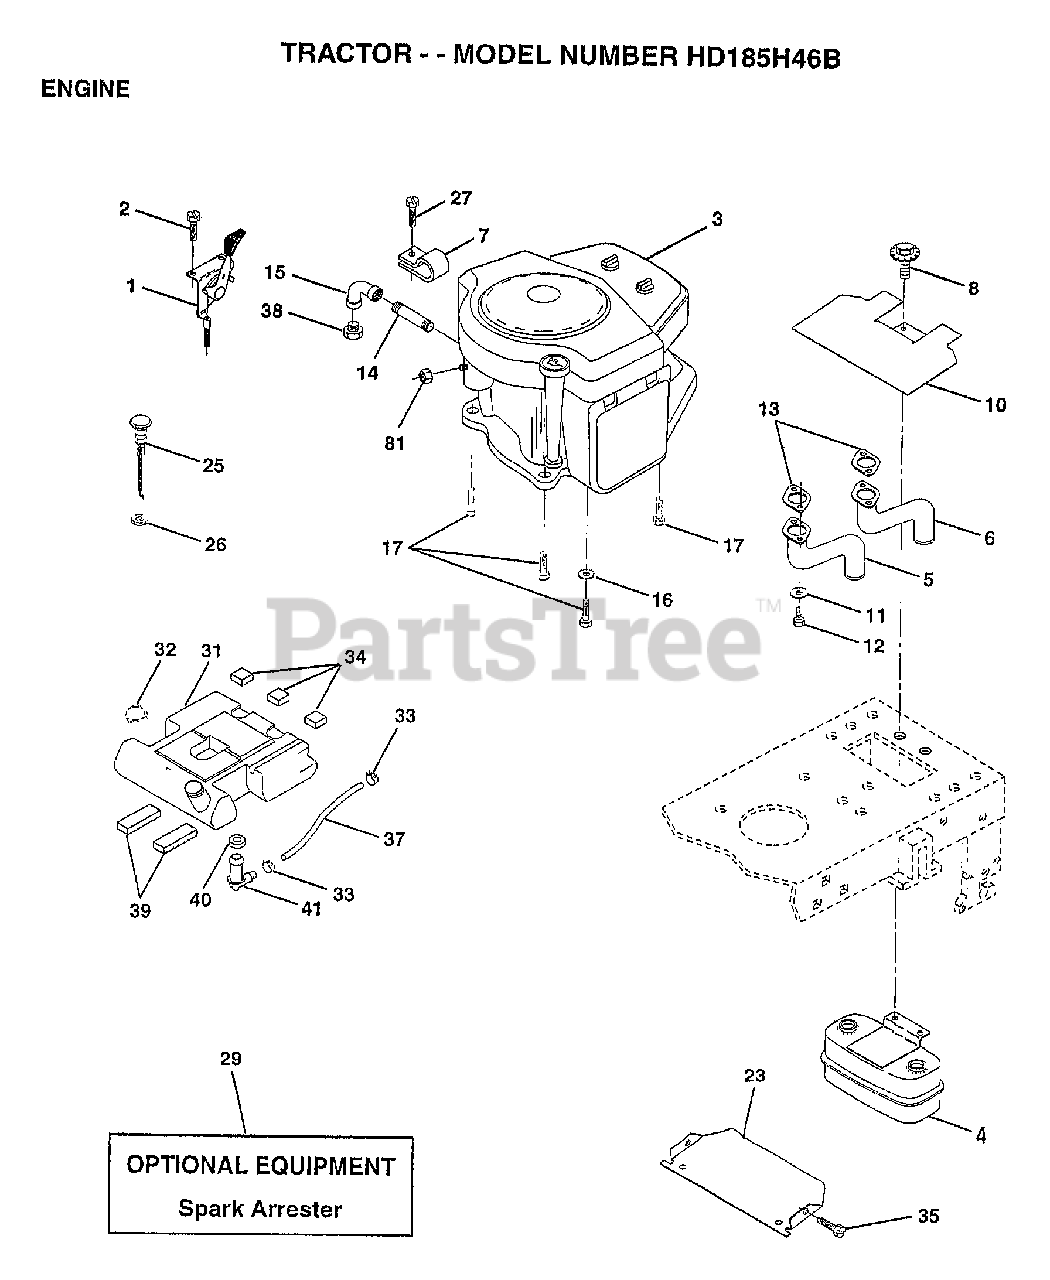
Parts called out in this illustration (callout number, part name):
1	CONTROL THRT 35.5
2	SCREW LT
4	MUFFLER.TW.LOTONE
5	EXHAUST.B&S.18.RH
6	EXHAUST.B&S.18.LH
7	CLAMP.TUBE.DBL.EN
8	BOLT.5/16-18.UNC
10	SHIELD.HEAT.
11	LOCKWASHER
13	GASKET MUFFLER
14	PIPE NIPPLE LT
15	ELBOW
16	LOCKWASHER
17	SCREW LT
23	SHIELD-HEAT
25	CONTROL.CHOKE.37
26	"NUT,KEPS 3/8-24IM"
27	"SCREW-TT,10-32 FL"
31	TANK FUEL REAR
32	CAP ASM FUEL
33	HOSE CLAMP
34	PAD-SPACER LT
35	SCREW
37	FUEL LINE T
39	PAD IDLER TI
40	BUSHING OUTLET T
41	STEM.TANK.FUEL
81	NUT
